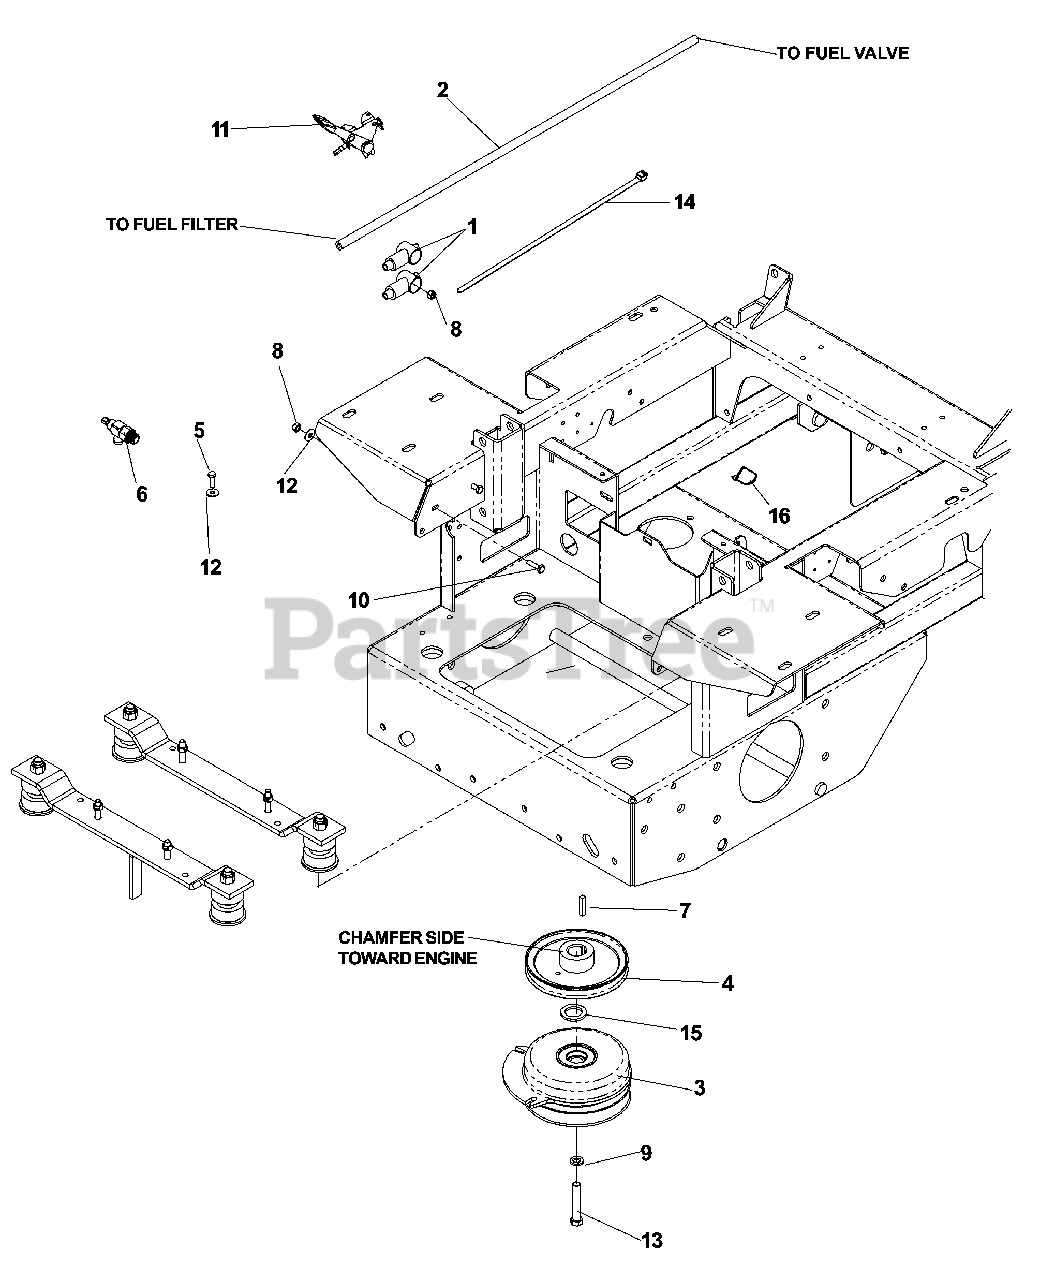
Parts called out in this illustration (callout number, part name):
1	INSULATOR
2	FUEL LINE 24"
3	CLUTCH-200 FT LB(RPLS 5218-102
5	HEX HEAD SCREW M6 X 1 X 20
6	OIL DRAIN ADAP.(HONDA)
7	KEY, 1/4 SQ X 1 1/4
8	NUT 1/4-20 NYLOC
9	WASHER 7/16 LOCK
10	HCS 1/4 X 1
11	CABLE CHOKE
12	WASHER 1/4 FLAT
13	BOLT 7/16F X 2 1/2
14	TIE-PLASTIC 15X120#
15	BUSHING, 10GA MACHINERY
16	TIE, PLASTIC
